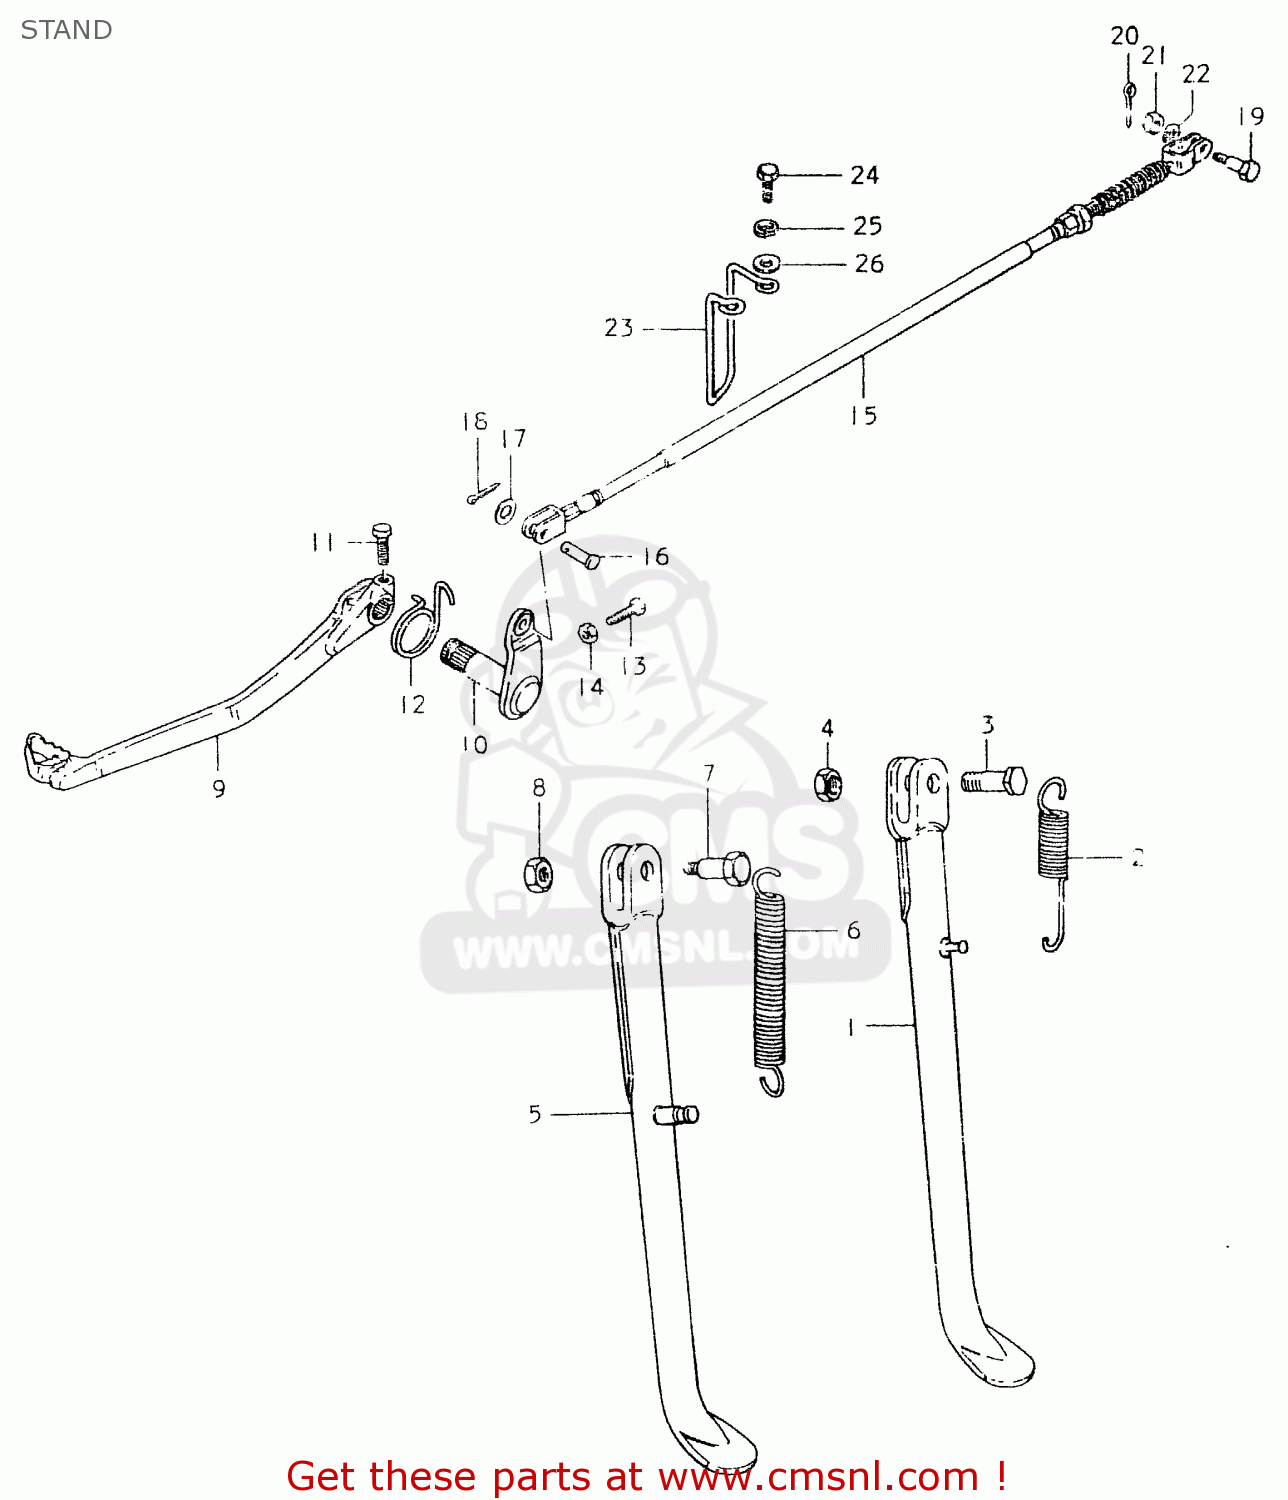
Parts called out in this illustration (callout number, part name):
1	STAND,SIDE
2	SPRING
3	BOLT(10X30)
4	NUT
5	STAND, PROP
6	SPRING
7	BOLT
8	NUT
9	PEDAL,BRAKE
10	ARM,BRAKE PEDAL
11	BOLT
12	SPRING
13	BOLT(6X23)
14	NUT
15	CABLE,RR BRAKE
16	PIN(L:17.5)
17	WASHER
18	PIN
19	BOLT
20	PIN
21	NUT
22	SHIM (8.5X16,5X0.8)
23	GUIDE,BRAKE CABLE
24	BOLT
25	LOCK WASHER
26	WASHER
